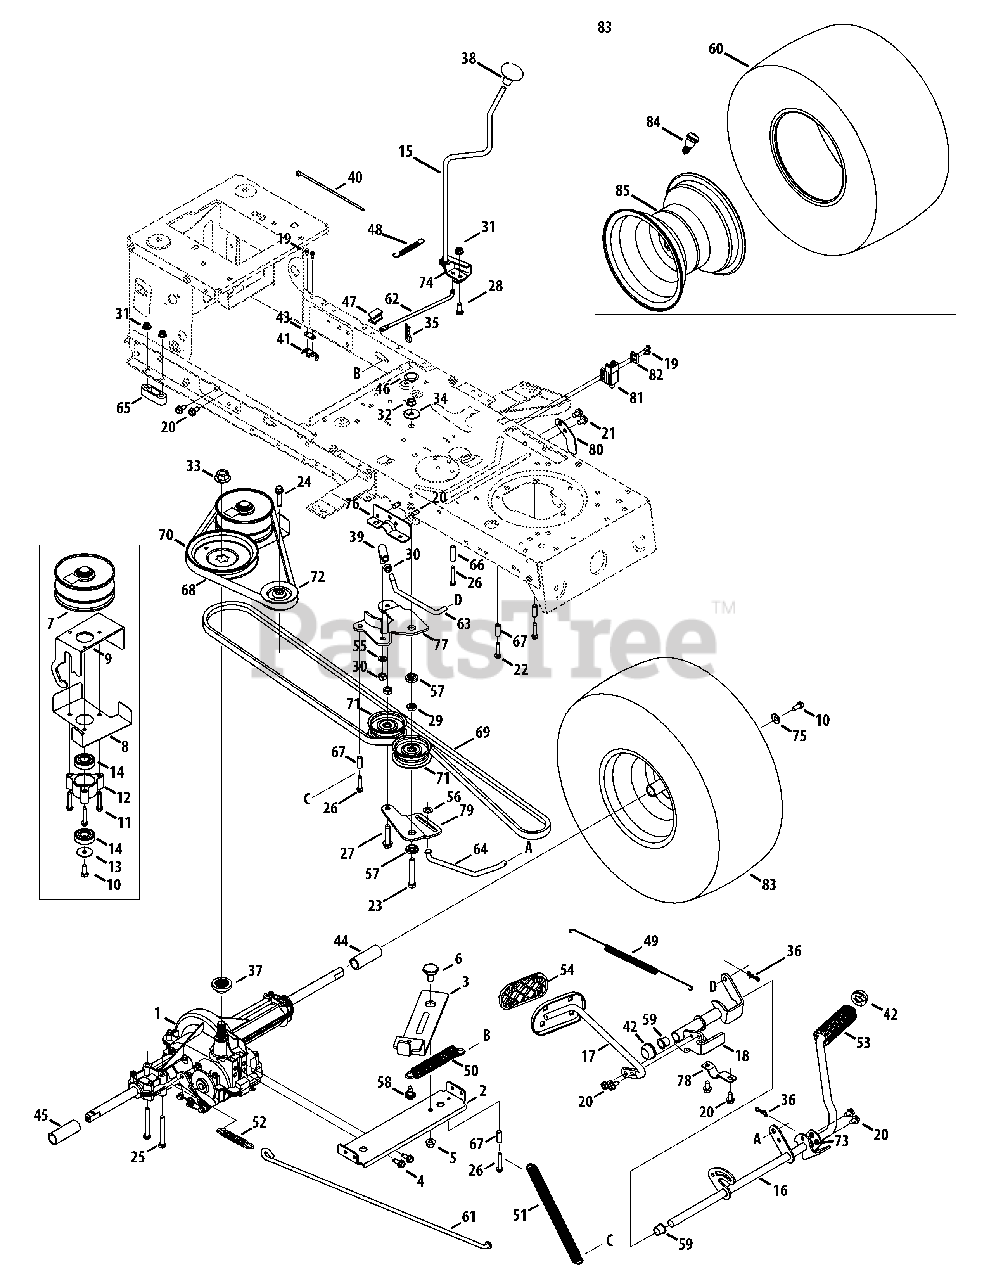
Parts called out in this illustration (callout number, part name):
1	Drive Assembly, Autodrive
2	Auto-drive Bracket Assembly
3	Idler Bracket Assembly
4	Tap Screw, 5/16-18 x 0.750
5	Flange Lock Nut, 3/8-16
6	Shoulder Screw, .625 x .217
7	Pulley Assembly, Var. Spd. 4.75 Od
8	Belt Keeper Assembly
9	Variable Bracket Assembly
10	Hex Screw 5/16-24 .750
11	Tap Screw, 1/4-20 1.500
12	Bearing Cup
13	Washer, Flat .330 X 1.25 X .06
14	Ball Bearing, 17 x 40 x 12.6203
15	Lever Assembly, Shft
16	Pedal Assembly, Drive, Autodrive
17	Pedal Assembly, Cont, Autodrive
18	Bracket Assembly, Pedal, Autodrive
19	Screw, Ab, #8-18, 0.500
20	Screw, Tt, 5/16-18, .750
21	Screw, Tt, 5/16-18, 0.625
22	Screw, Tt, 1/4-20, 1.250
23	Hex Hd. Screw, 3/8-16, 2.50
24	Screw, Ttsems, 3/8-16, 1.500
25	Hex Hd. Screw, 5/16-18, 3.50
26	Screw, Tt, 1/4-20, 1.625,
27	Screw, Tt, 3/8-16 x 1.75
28	Hex Hd. Screw, 5/16-18, .75
29	Nut, Jam, 7/16-20
30	Nut, Hex, 3/8-24
31	Nut, Flange Lock Nut, 5/16-18
32	Nut, Flange Lock Nut, 3/8-16
33	Nut, Flg, 9/16-18
34	Washer, Flat, .406 x 1.920 x .060
35	Pin, Cotter Int- .125 Dia
36	Pin, Cot, Bow-Tie 72
37	Hub, Pulley, 5/8 Spline
38	Knob, Shft
39	Ball, Joint
40	Cable, Tie, 3/16 X .05 X 7.4
41	Switch, Spring, Short
42	Cap, Push 5/8
43	Plate, Insulator Nut
44	Sleeve, .758 X .821 X 3.3125
45	Sleeve, .758 X .821 X 2.4375
46	Plug, Deck Hole, 7/8
47	Shift Plate Bearing
48	Spring, Ext, .38 Od X 3.25 Lg
49	Spring, Extn, .70 Dia X 12.00 Lg
50	Spring, Extn, .97 Od X 6.18 Lg
51	Spring, Extn, .56 X 12.05 x .068
52	Spring, Extn, .59 Od X 4.00 Lg
53	Pad, Foot, 4.0 Long
54	Pad, Cont
55	Washer, Lock, 3/8, Regular Duty
56	Washer, Flat, .375 X .738 X .063
57	Spacer, Shoulder, 1.00 X .38 X .38
58	Screw, Shoulder, .43x.29, Tt, 5/16-18
59	Bearing, Flg, .630 Idx .695 Od X .60
60	Tire, 20 x 8 x 8 Sq. Sh.
61	Rod, Brake, Lt-5 Trans
62	Rod, Shift, Lt-5 Stretch 46"
63	Rod, Adj, Idlr, 3/8
64	Rod, Trans, Footpedal Bypass
65	Spacer, T-Axle .68
66	Spacer, .260 X .372 X 1.420 Lg
67	Spacer, .260 X .375 X 1.030 Lg
68	Belt, V Typ, 5l X 40.9 Lg Poly
69	Belt, V Typ, 5l, 90.80, Poly
70	Pulley, Idlr, Flat 7.25 Od
71	Pulley, Idlr, Flat 2.75 Od
72	Pulley, Idlr, V-Type X 3.06
73	Bracket, Pedal, Support
74	Bracket, Shft, Adj
75	Bell Washer, .340 x .872 x .060
76	Bracket, Pedal, Frame Rh
77	Bracket, Idlr, Dbl Autodrive
78	Bracket, Supt, Pedal Stap
79	Bracket, Idlr, Center Dbl
80	Pedal Stop Plate
81	Interlock Switch
82	Switch Plate
83	Wheel Assembly, 20 x 8 x 8 Sq. Shoulder
84	Valve Stem
85	Rim Assembly
